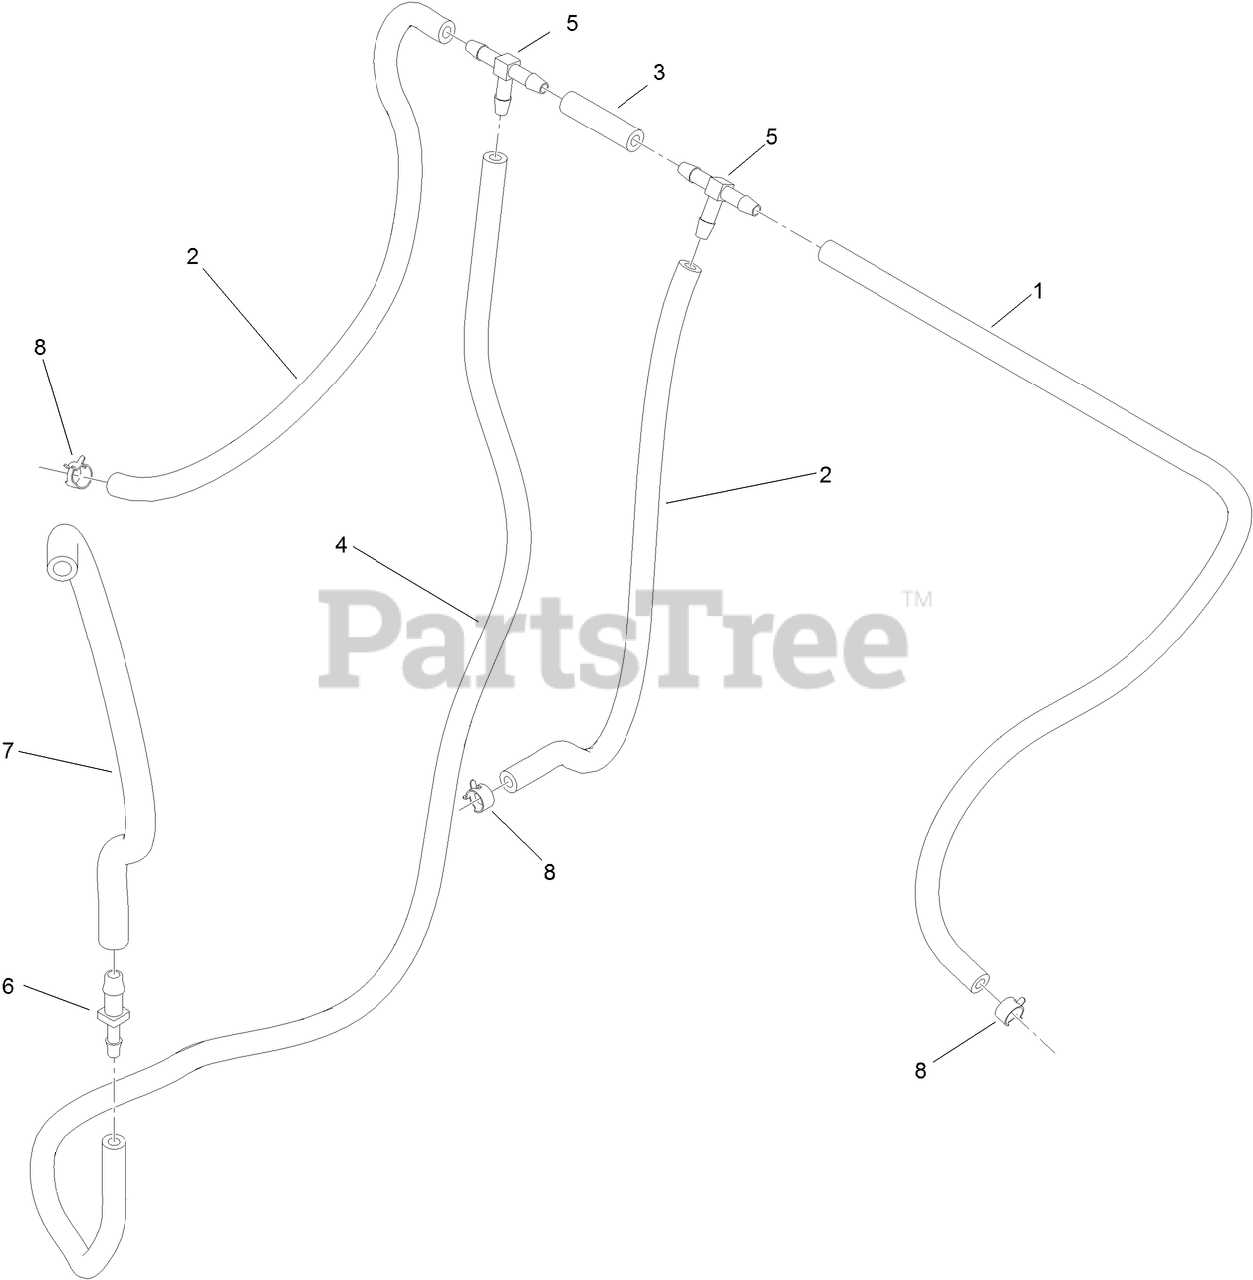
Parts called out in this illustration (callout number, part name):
1	HOSE-FUEL
2	HOSE-FUEL
3	HOSE-FUEL
4	HOSE-FUEL
5	FITTING-TEE, BARBED
6	FITTING-STRAIGHT
7	HOSE-FUEL
8	CLAMP-HOSE
